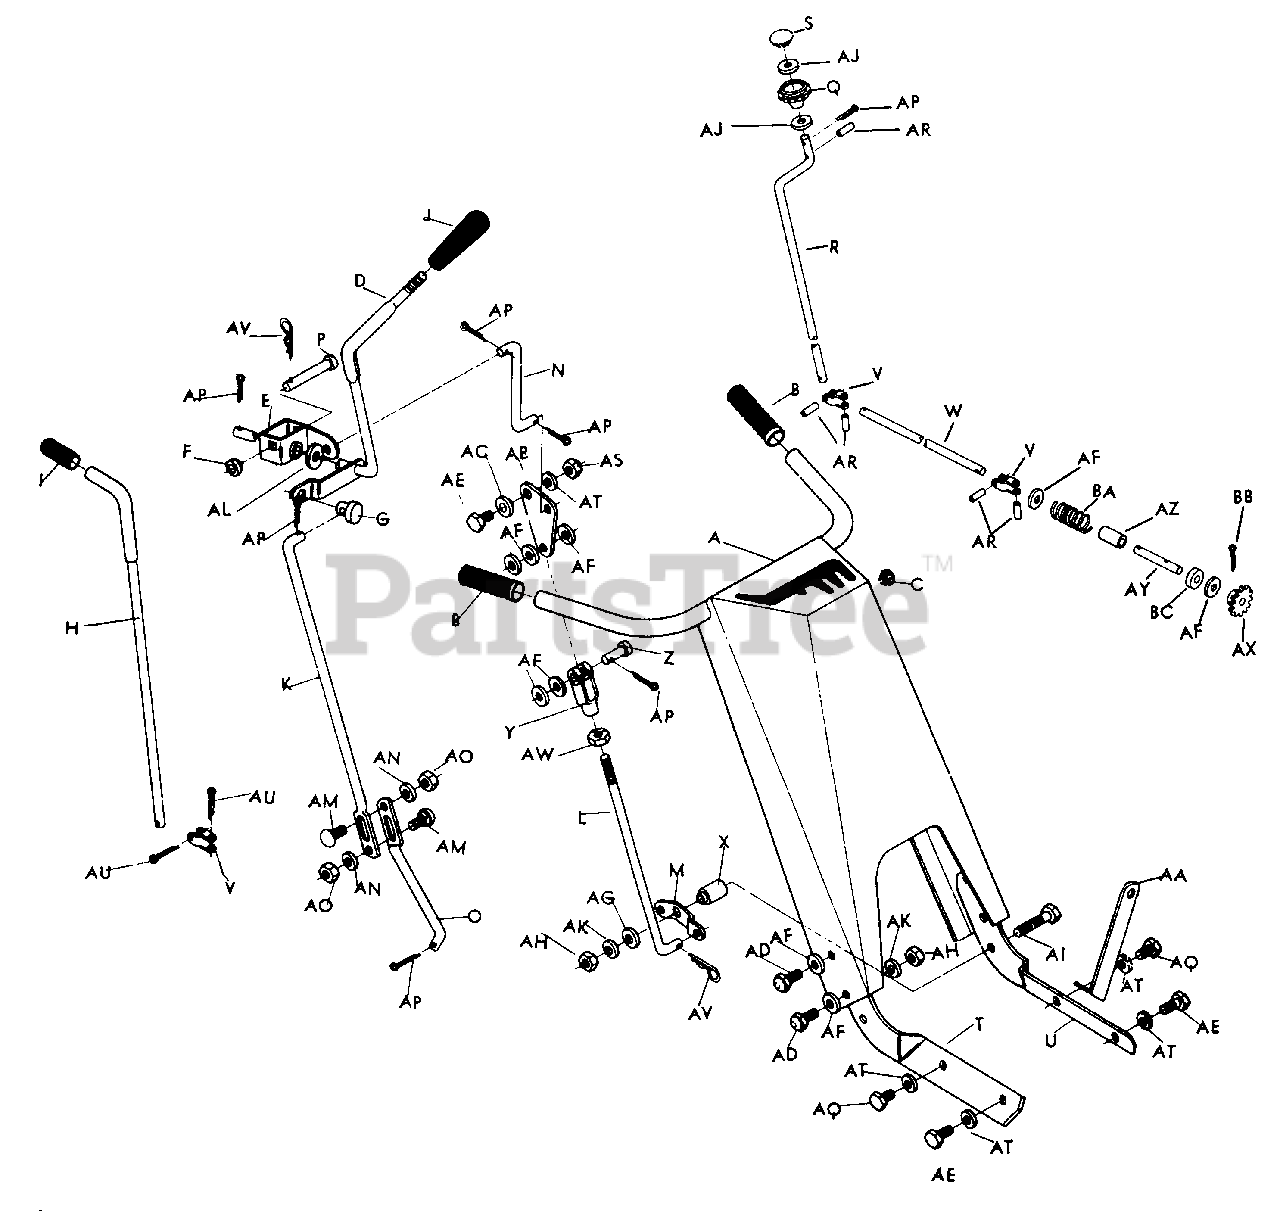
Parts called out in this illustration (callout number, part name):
A	Handle Bar Assembly
B	Grip
C	Plug Button
D	Control Lever Assembly
E	Bracket Assembly w/Bushings-Control Lever
F	Bushing
G	Pivot Pin
H	Auger Clutch Rod Assembly
I	Grip
J	Control Knob
K	Shifter Rod
L	Traction Clutch Rod
M	Bellcrank
O	Shifter Rod End
P	Clevis Pin
Q	Knob
R	Crank-Chute Control
S	Plug-Knob
T	Handle Bracket-R.H.
U	Handle Bracket-L.H.
V	Universal
W	Chute Shaft
X	Pivot Bushing
Y	Clevis
Z	Clevis Pin
AA	Chute Shaft Support
AB	Bellcrank
AC	Pivot Bushing
AD	3/8-16 x 1 Acorn Hd. Bolt-Pl.
AE	5/16-18 x 1 Hex Hd. Capscrew-Pl.
AF	3/8 Flat Washer-Pl.
AG	5/16 Flat Washer-Pl.
AH	3/8-16 Hex Nut-Pl.
AI	3/8-16 x 2 1/4 Hex Hd. Capscrew-Pl.
AJ	3/8 SAE Flat Washer-Pl.
AK	3/8 Lockwasher-Pl.
AL	7/16 SAE Flat Washer-Pl.
AM	1/4-20 x 3/4 Carriage Bolt-Pl.
AN	1/4 Lockwasher-Pl.
AO	1/4-20 Hex Nut-Pl.
AP	1/8 x 3/4 Cotter Pin-Pl.
AQ	5/16-18 x 3/4 Hex Hd. Capscrew-Pl.
AR	1/8 x 3/4 Roll Pin-Pl.
AS	5/16-18 Cone Locknut-Pl.
AT	5/16 Lockwasher-Pl.
AU	1/8 x 1 Cotter Pin-Stainless Steel
AV	Spring Clip
AW	3/8-16 Hex Jam Nut-Pl.
AX	Sprocket Assembly
AY	Sprocket Shaft
AZ	Spacer
BA	Spring
BB	1/8 x 1 1/2 Cotter Pin-Stainless Steel
BC	Rubber Washer
